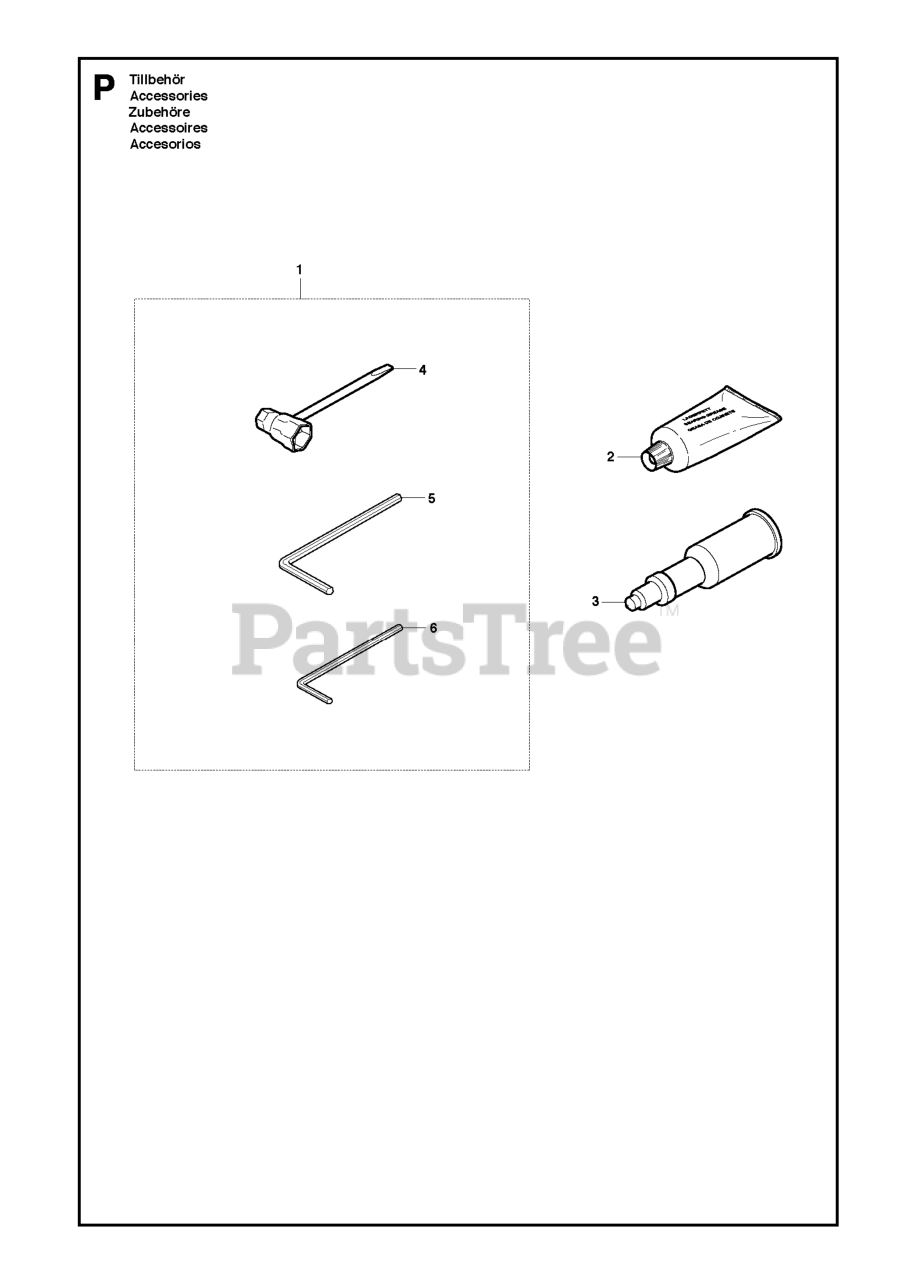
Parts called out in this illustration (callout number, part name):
1	TOOL KIT
2	GREASE
3	Grease Gun
4	COMBI TOOL
